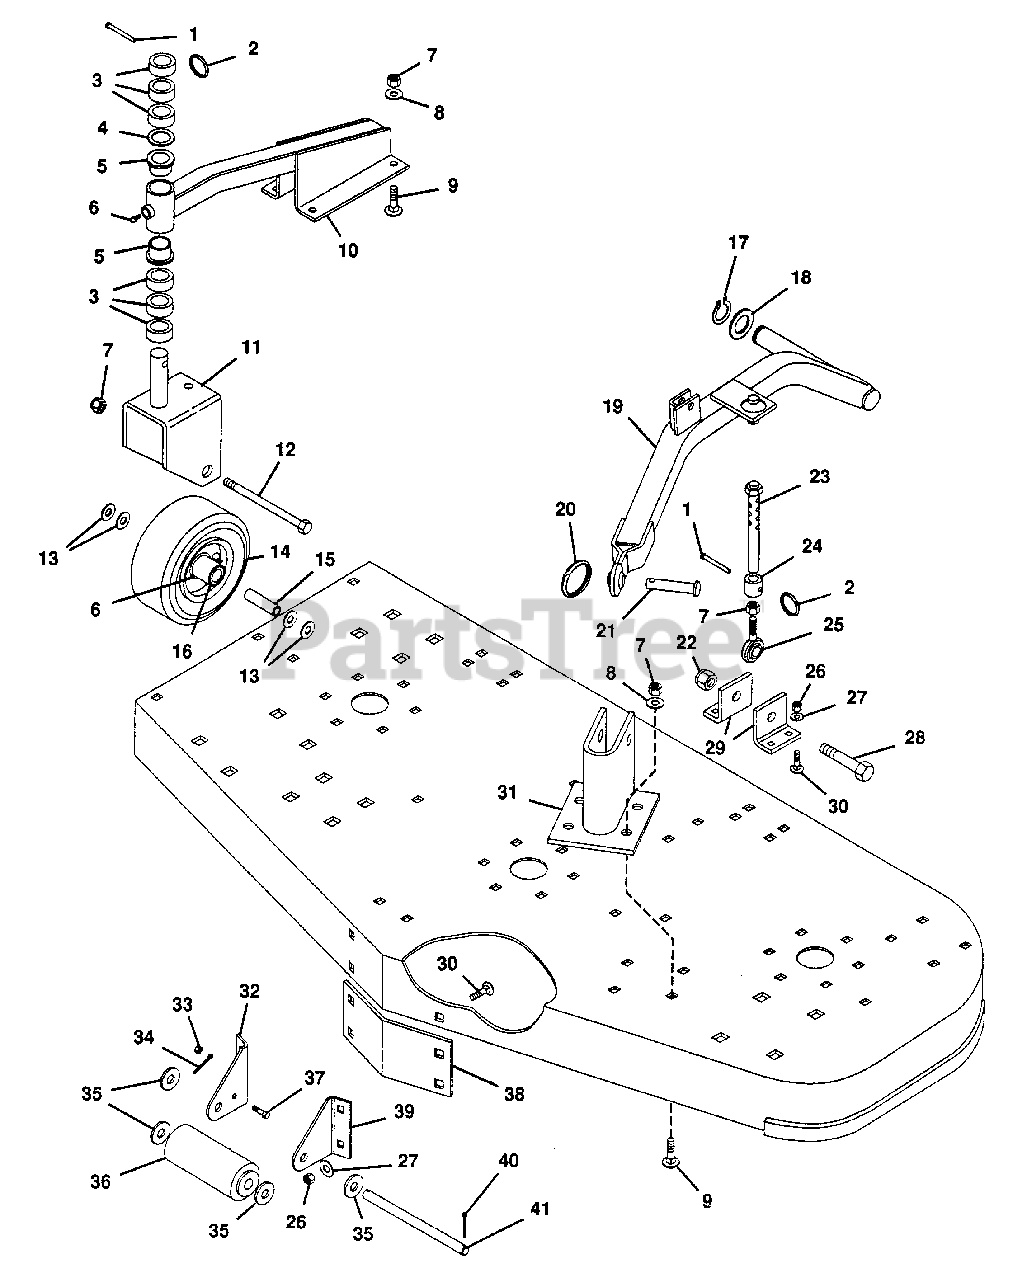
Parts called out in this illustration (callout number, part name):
1	Pin, Clevis .31x2.25
2	Ring, Split 1.25
3	Bush., St. 1.07x1.75x.50 Stl.
4	Race, Bearing Thrust
5	Bush., Flg. 1.03x1.75x.750 Ny.
6	Fitting, Lube 1/4-28
7	Nut, Lock 1/2-13
8	Washer, Flat .531x1.062x.095
9	Bolt, 1/2-13x1.50 Rd Hd Sq Nk
10	Weldment, Caster Wheel Support
11	Weldment, Caster Fork
12	Bolt, Hex 1/2-13x5.50
13	Washer, Flat .531x1.250x.100
14	Wheel, Gauge
15	Bush., St. .506x.748x3.34 Stl.
16	Bearing, Ball
17	Ring, Retaining
18	Bearing, Thrust Race
19	Weldment, Mower Arm L.H.
19	Weldment, Mower Arm R.H.
20	Ring, Split 2.25
21	Pin, Clevis .87x2.40
22	Nut, Lock 3/4-10
23	Weldment, Height Adjustment
24	Bush., St. .765x1.25x.910 Stl.
25	Rod, End
26	Nut, Lock 3/8-16
27	Washer, Flat .406x.812x.065
28	Bolt, Hex 3/4-10x3.5
29	Bracket, Deck Support Rear
30	Bolt, 3/8-16x1.00 Rd Hd Sq Nk
31	Wldmnt, Mwr Mounting Arm Brckt
32	Bracket, Roller R.H.
33	Nut, Hex 1/4-20
34	Pin, Cotter .250x2.00
35	Washer, Flat .656x1.312x.095
36	Roller, Gauge
37	Bolt, Hex 1/4-20x.75
38	Plate, Deck Reinforcement
39	Bracket, Roller L.H.
40	Pin, Cotter .25x1.00
41	Shaft, Center Roller
